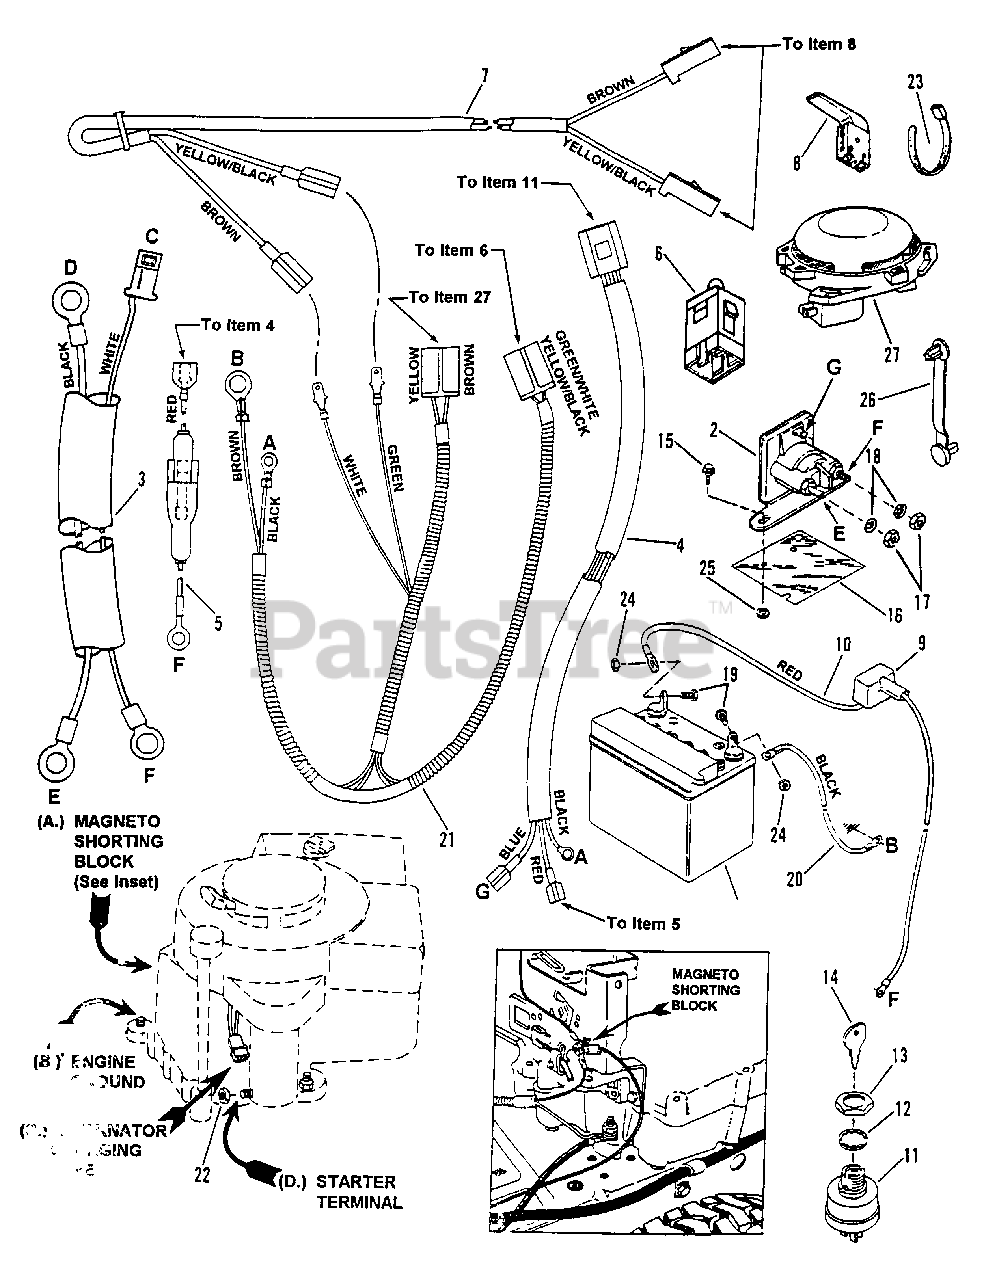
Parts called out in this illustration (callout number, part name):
2	SOLENOID
3	HARNESS, Starter Wiring (Briggs)
4	HARNESS, Ignition Wiring (Briggs)
5	HOLDER, Fuse
6	SWITCH, Traction Operator's Presence
7	HARNESS, (Deck Interlock Wiring)
8	SWITCH, Deck Interlock
9	COVER, Battery Cable
10	CABLE, Positive (Red)
11	SWITCH, Ignition
12	WASHER, 5/8 Internal Tooth Lock
13	NUT, 5/8-32 Hex
14	KEY, Switch
15	SCREW, 1/4-20 x 1/2" Self-Tapping
16	PROTECTOR, Solenoid
17	NUT, 1/4-20 Hex
18	WASHER, 1/4 Internal Tooth Lock
19	SCREW, 1/4-20 x 5/8" Hex Head Cap
20	CABLE, Negative
21	HARNESS, Operator Presence Control Wire
22	NUT, 1/4-20 Hex
23	TIE, 7" Long Cable
24	NUT, 1/4-20 Hex Lock
25	RETAINER, 1/4 Bolt
26	TIE, 2" Long Cable
27	SWITCH, Seat
